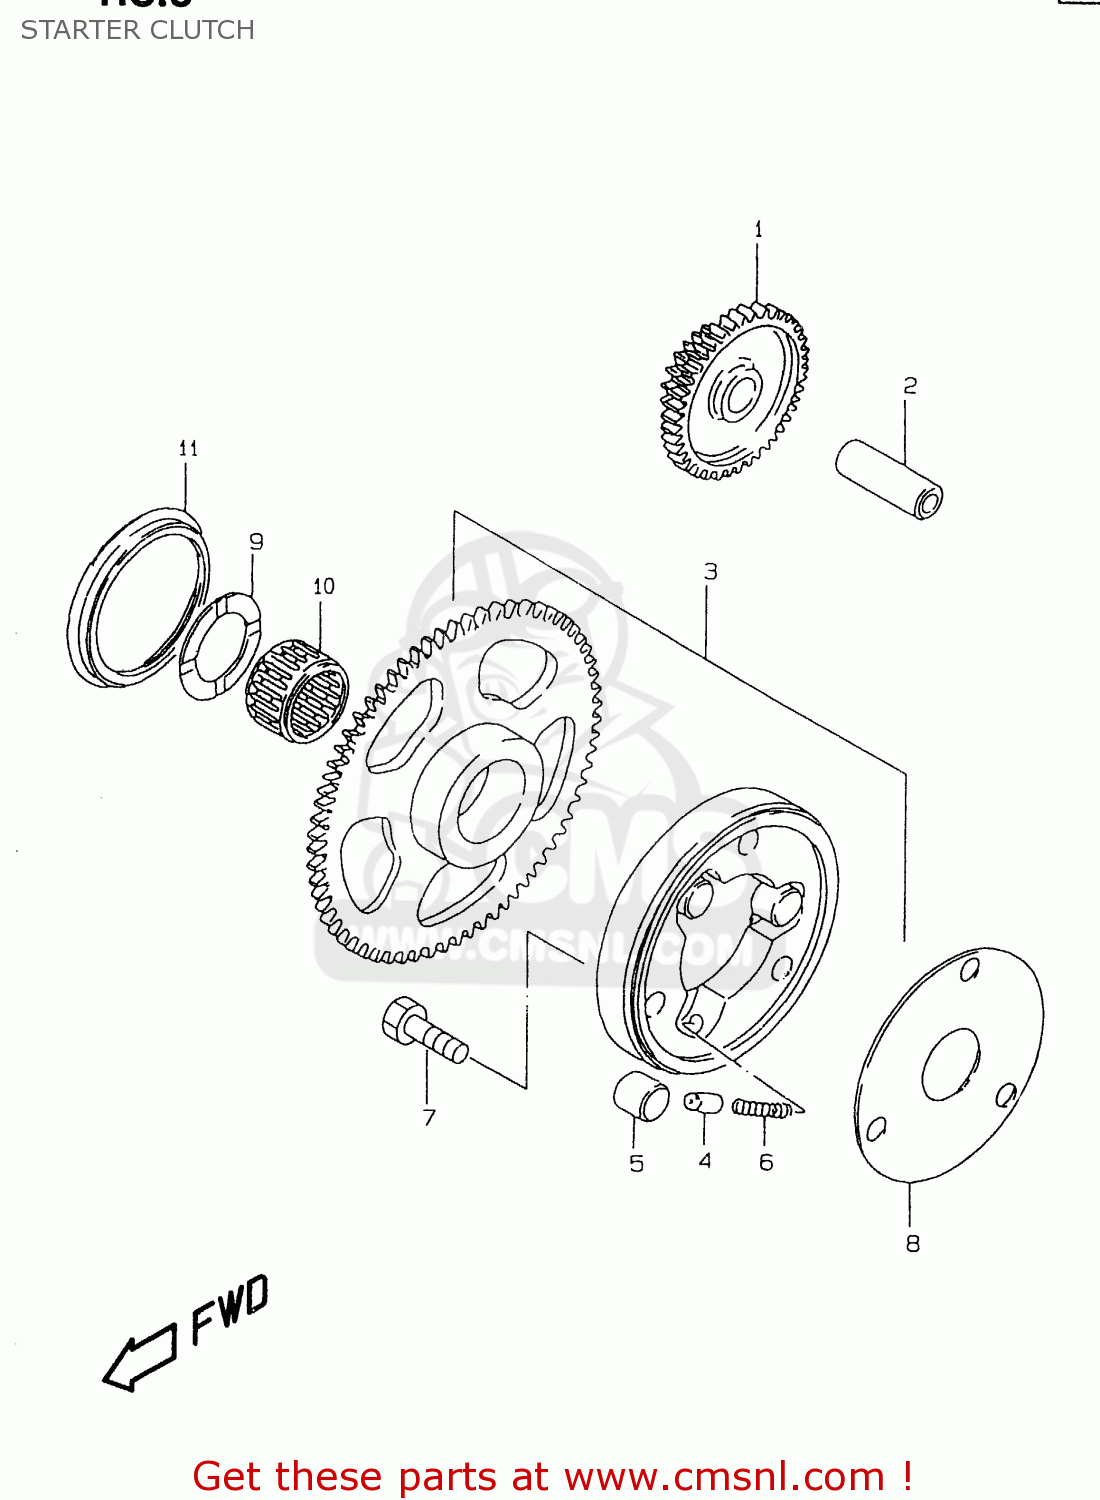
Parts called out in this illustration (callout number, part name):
1	GEAR,STARTER IDLE
2	PIN(7.4X13X40)
3	CLUTCH SET,STARTER
4	PIECE,PUSH
5	PIN(14X13)
6	SPRING
7	BOLT
8	SHIM,STARTER CLUTCH HUB
9	WASHER(27X40X2.5)
10	BEARING(27X32X21.8)
11	SEAL,OIL(52X62X6.8)
